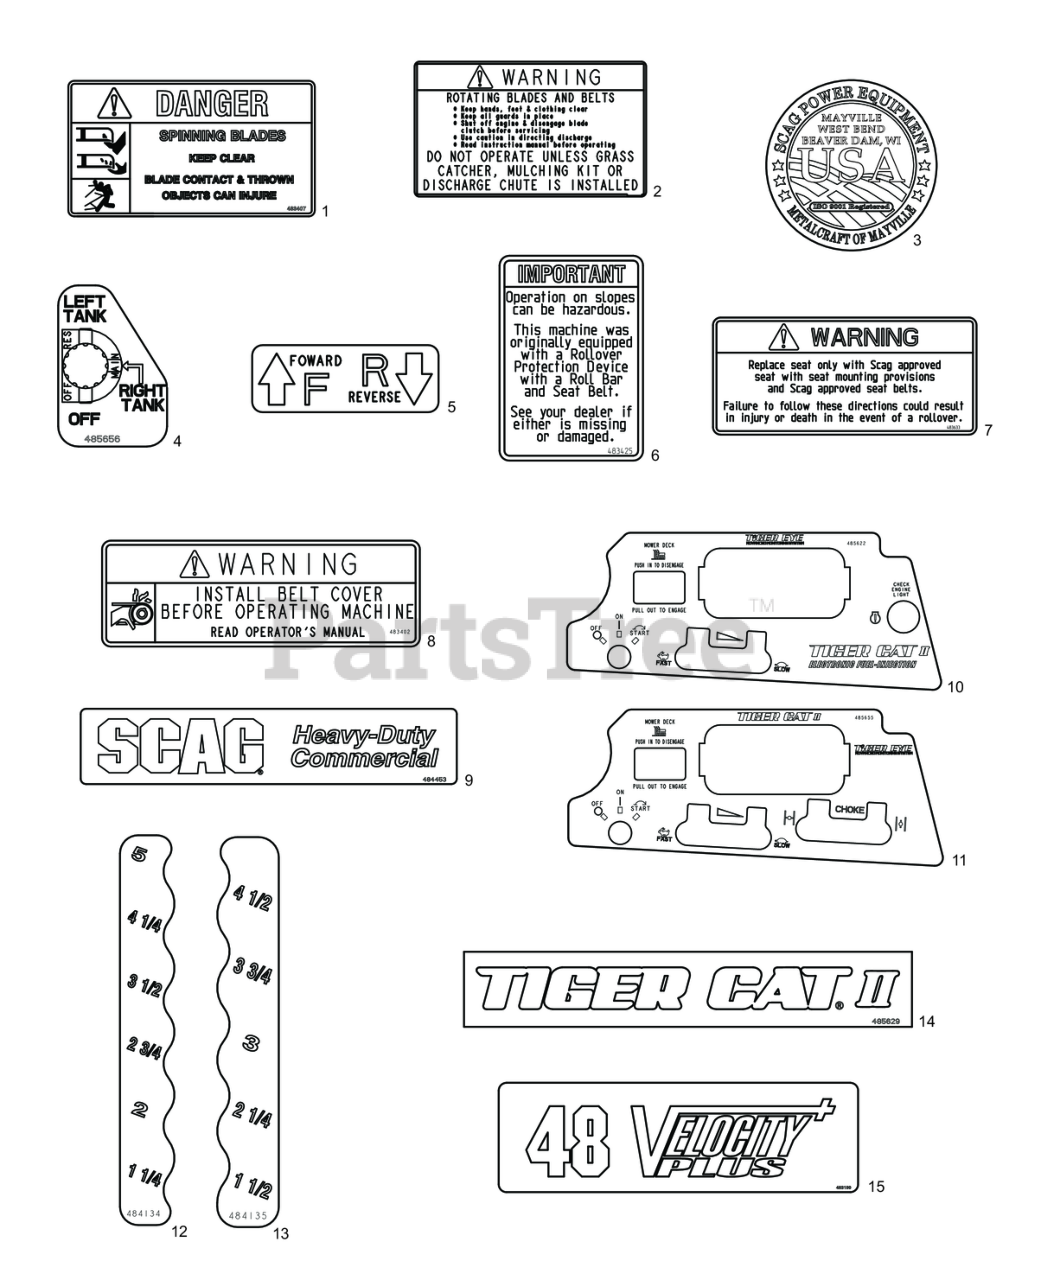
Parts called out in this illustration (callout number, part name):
1	Decal, Danger-Spinning Blades
2	Decal, Warning - Rotating Blades
3	Decal, Metalcraft - USA
4	Decal, Fuel Valve Position
5	Decal, Traction Control
6	Decal, ROPS
7	Decal, Seat Replacement
8	Decal, Warning - Belt Cover
9	Decal, Scag Heavy Duty Commercial
10	Decal, Instrument Panel - EFI
10	Decal, Instrument Panel - Kawasaki EFI
11	Decal, Instrument Panel
12	Decal, Deck Height - LH
13	Decal, Deck Height - RH
14	Decal, Tiger CatII
15	Decal 52V 483201 Decal 61V
